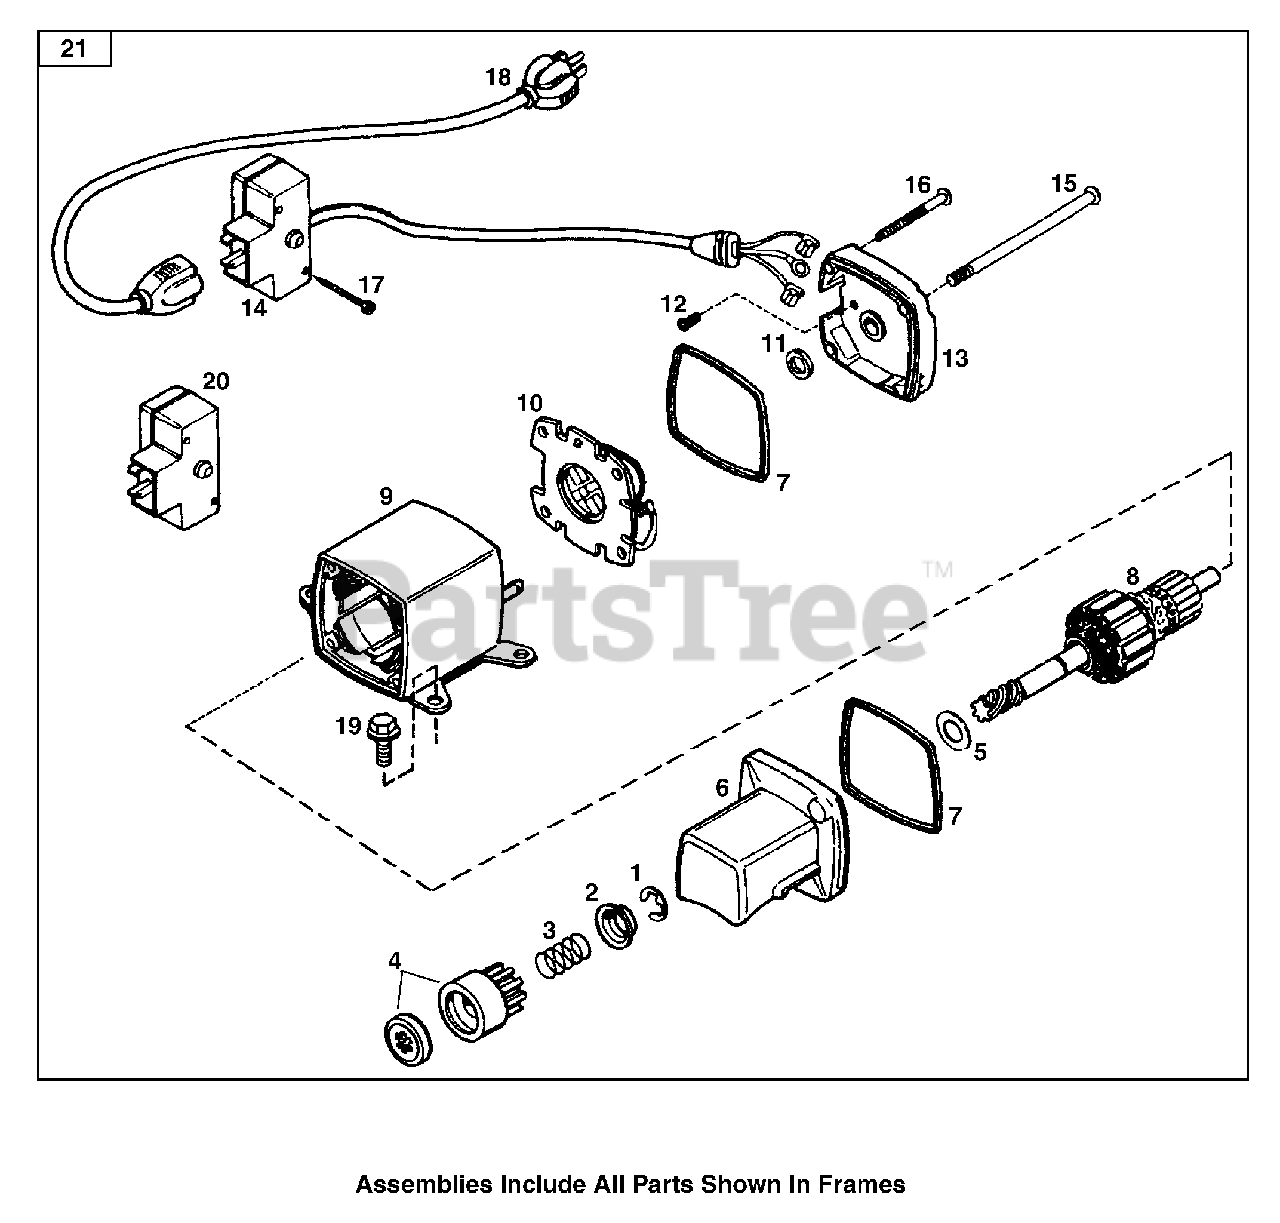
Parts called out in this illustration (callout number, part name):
1	Retainer Ring
2	Spring Retainer
3	Anti-Drift Spring
4	Nut & Gear
5	Thrust Washer
6	Drive End Cap Ass’y
9	Housing Ass’y
10	Brush & Spring Card Ass’y
11	Thrust Washer
12	Ground Screw
13	Commutator End Cap Ass’y
14	Switch Box Ass’y
15	Case Bolt
16	Grounding Screw
17	Screw, 6-32 x 2-1/2".
18	Extension Cord
19	Screw, Torx T-30, 1/4-20 x 23/32".
20	Switch Repair Kit
21	Electric Starter (110 Volt)
